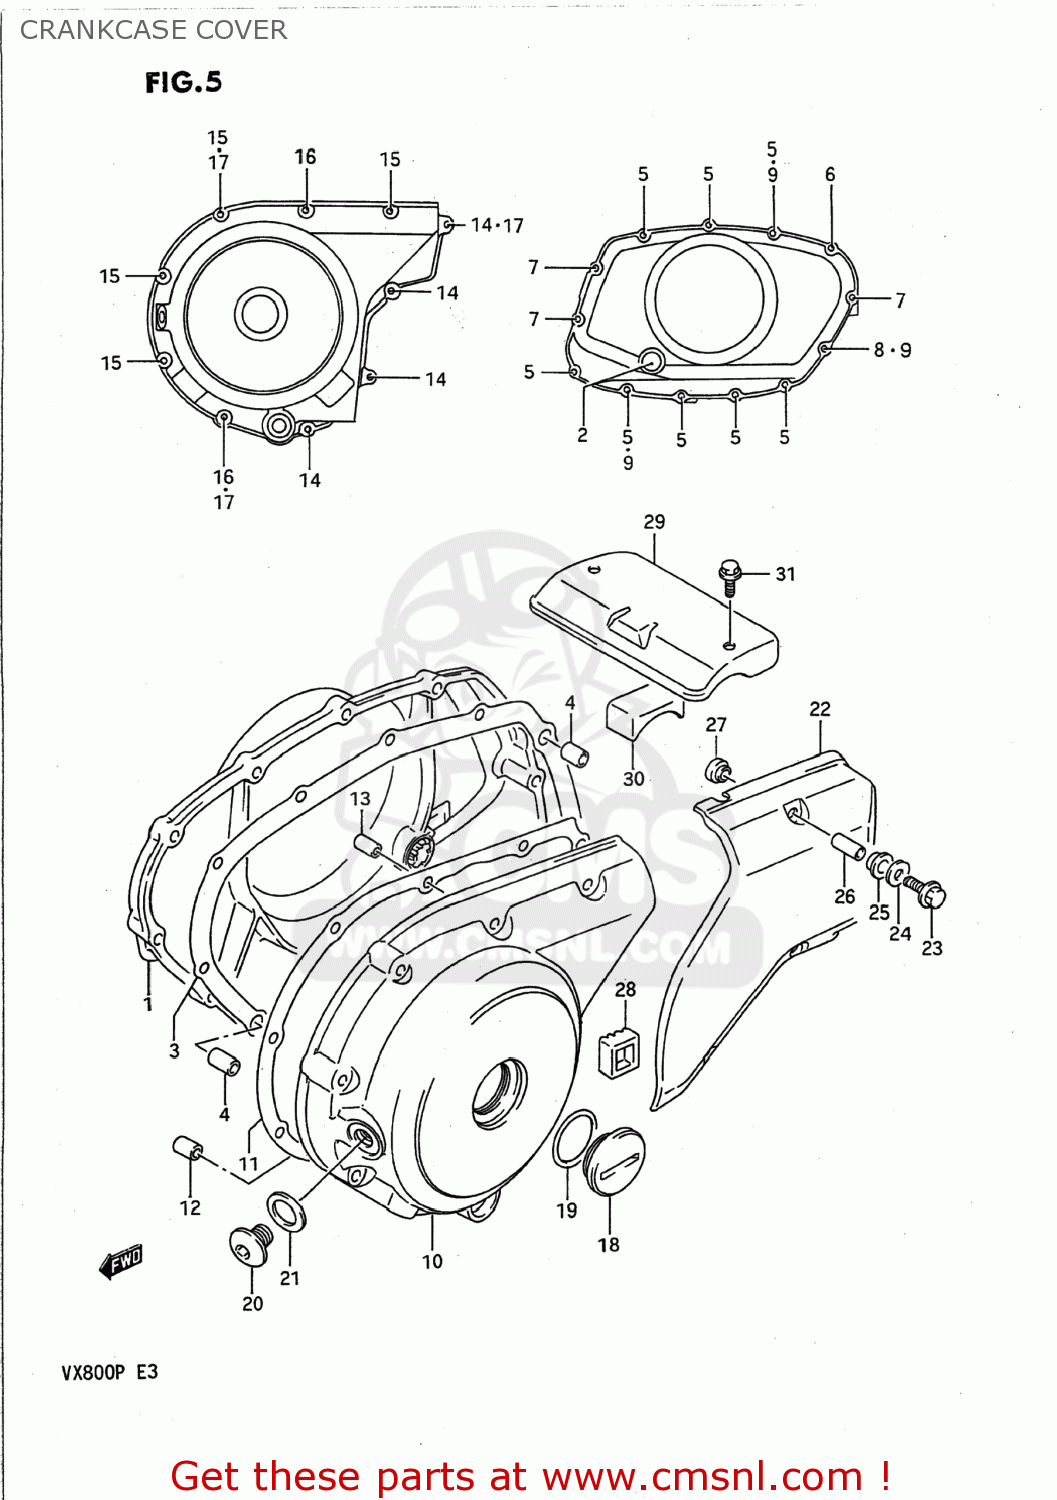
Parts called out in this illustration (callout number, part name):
1	COVER,CLUTCH
2	LENS,OIL LEVEL CHECK
3	GASKET,CLUTCH COVER (NAS)
4	PIN
5	BOLT
6	BOLT
7	BOLT
8	BOLT
9	GASKET(5.8X13X1.2) (NAS)
10	COVER
11	GASKET,MAGNETO COVER (NAS)
12	PIN (11X20)(SUS)
13	PIN
14	BOLT
15	BOLT
16	BOLT
17	GASKET(5.8X13X1.2) (NAS)
18	PLUG
19	O RING(D:3.1,ID:32.7)
20	PLUG,14X12
21	GASKET(14X19.2X2) (NAS)
22	COVER,SPROCKET
23	BOLT
24	WASHER
25	WASHER(8.7X15X2.1)
26	SPACER
27	WASHER(8.7X16X5)
28	DAMPER,SECONDARY COVER
29	COVER,STARTER MOTOR
30	DAMPER,MOTOR COVER
31	BOLT
